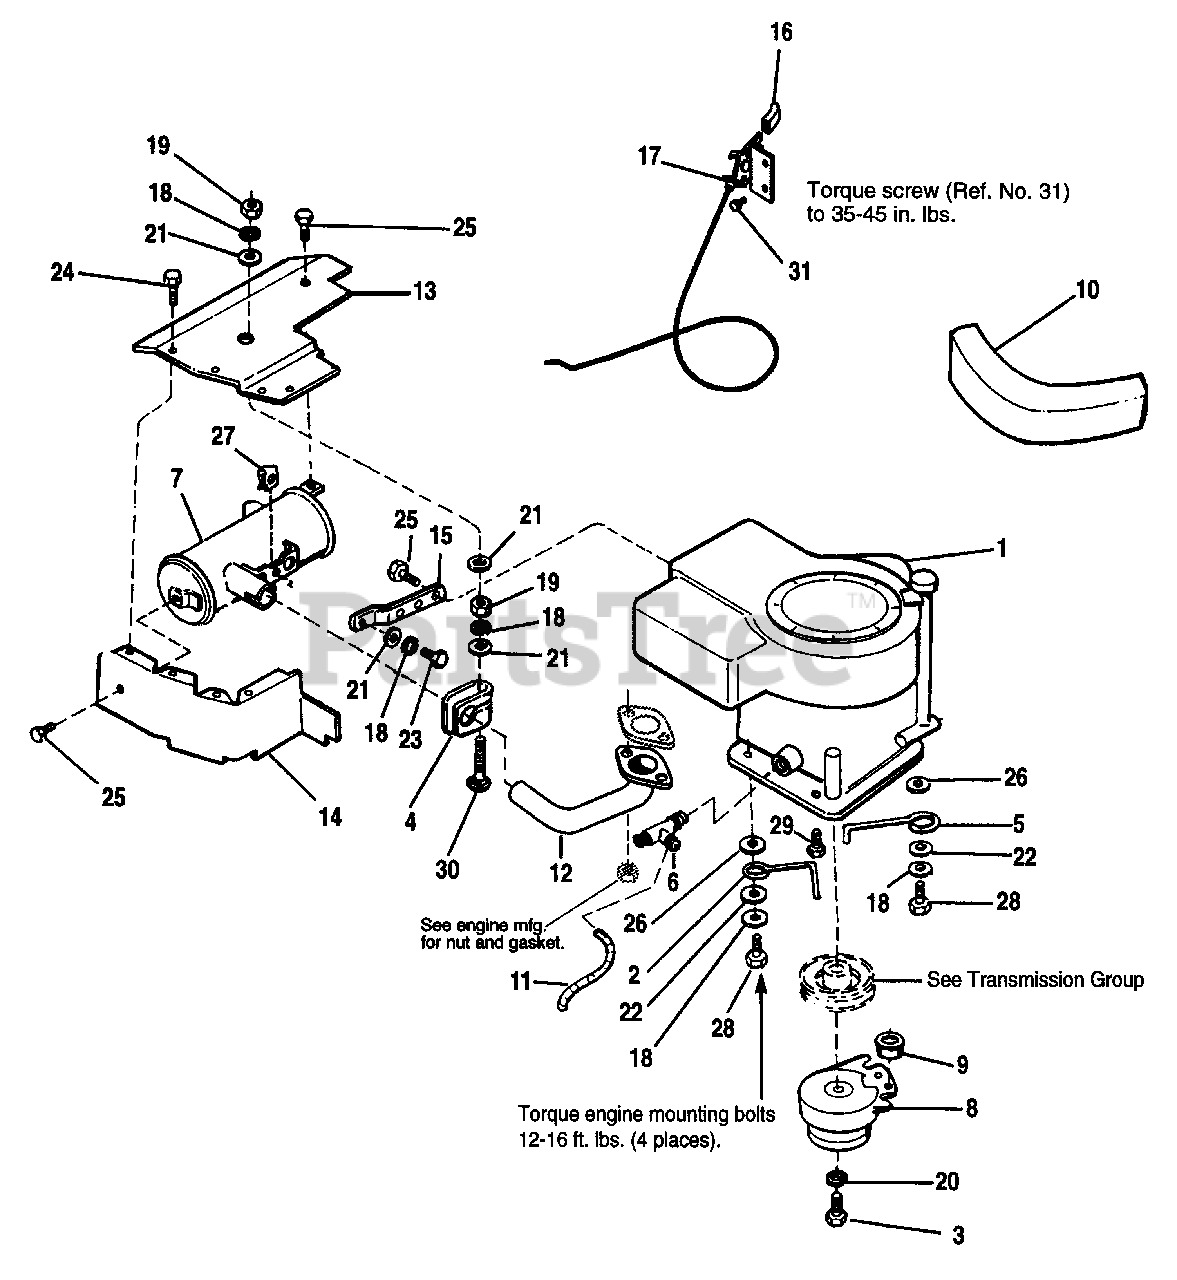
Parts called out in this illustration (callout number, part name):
1	ENGINE, 13 HP (Kohler)
3	CAPSCREW, Hex Hd., M10-1-1/2 x 60mm
4	CLAMP, Muffler
6	VALVE, Oil Drain
7	MUFFLER ASSY.
8	ELECTRIC CLUTCH
9	SLEEVE, Clutch Anchor
10	SEAL, Air Inlet
11	HOSE, Oil Drain
12	PIPE, Exhaust
13	SHIELD, Muffler
14	DUCT, Bottom
15	SUPPORT, Muffler
16	KNOB, Throttle Control
17	THROTTLE CONTROL ASSY.
18	LOCKWASHER, 5/16
19	NUT, Hex, 5/16-18
20	LOCKWASHER, 7/16
21	WASHER, 11/32
22	WASHER, Plain, 3/8
23	CAPSCREW, Hex Hd., 5/16-18 x 1
24	SCREW, Hex Hd., 10-16 x 3/8
25	SCREW, Hex, Flange, Taptite, 5/16-18 x 1/2
26	WASHER, Plain
27	NUT, Speed, 5/16-18
28	CAPSCREW, Hex Hd., M8 x 1-1/4 x 40mm
29	SCREW, Hex, #8-1-1/4 x 30mm
30	CARRIAGE BOLT, 5/16-3 x 1-1/4
31	SCREW, Plastite, 1/4-10 x 1/2
